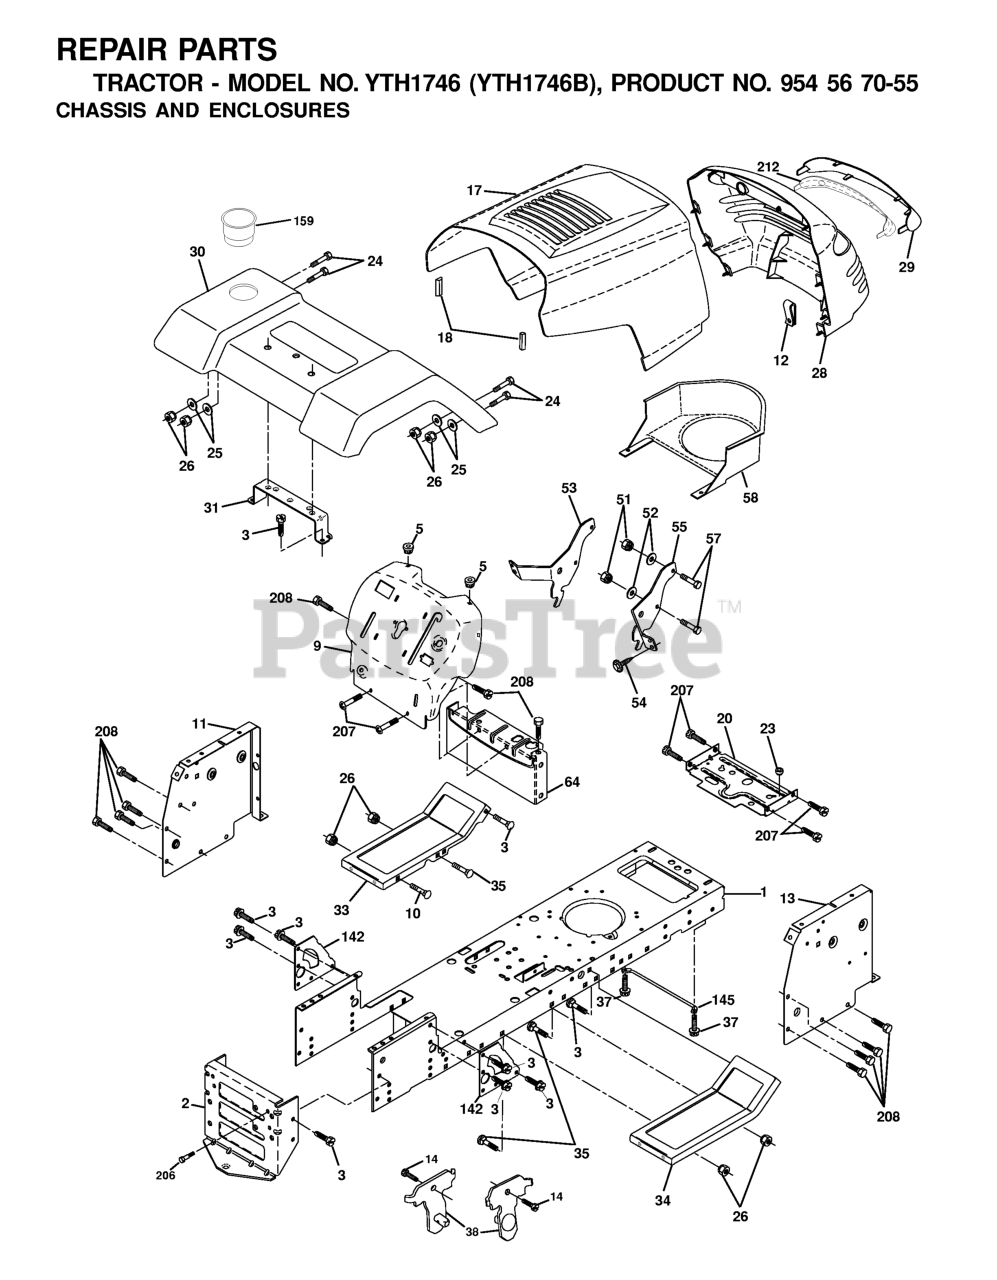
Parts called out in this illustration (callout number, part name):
1	CHASSIS STAMPING
2	DRAWBAR, 12GA
3	SCREW 3/8-16X3/4
5	BUMPER.RUBBER.HOOD
9	DASH SLKSCR
10	BOLT D
11	PANEL DASH LH
13	PANEL ASM, DASH RH
17	HOOD ASM.
18	BUMPER HOOD T
20	PLATE MTG
23	BUSHING.SNAP.NYL.BLK.
25	WASHER
26	NUT
28	GRILLE ASM
29	LENS
31	BRACKET FENDER
33	FOOT REST LH
34	FOOTREST RH
37	Screw 5/16-18 x 1/2 Hex, Self Tapping 5/16-18 x 1/2
38	BRACKET
51	LOCKNUT.NYLOC.1/4-20
53	BRACKET.GRILLE.LH
54	SCREW.HEX.WS.HD.8-18 X 7/8
57	BOLT
58	AIR DUCT P/L/LT
64	DASH LOWER
142	PLATE
145	ROD PIVOT CHASSIS/HOOD
206	SHOULDER BOLT 5/16-18TT
207	SCREW, 5/16-18 X 1/2
208	SCREW 3/8-16X1/2
212	REPL BY 532 1745-03
